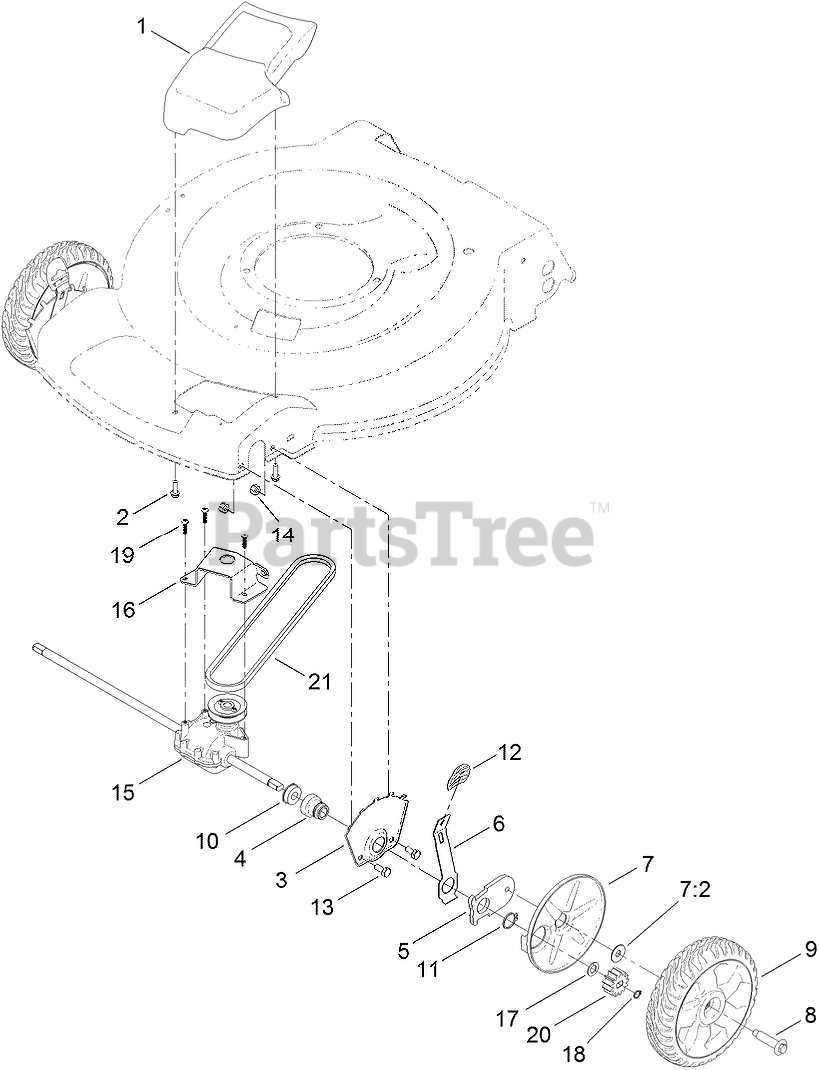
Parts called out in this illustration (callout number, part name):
1	COVER-BELT
2	SCREW-HWH
3	PLATE-HOC, FRONT
4	RETAINER-BEARING, HOC
5	ARM-PIVOT, FRONT
6	Arm-Spring
7	WHEEL COVER ASM
7:2	WASHER-STEPPED
8	BOLT-SHOULDER
9	8 INCH WHEEL ASM
10	BEARING-BALL
11	RING-RETAINING
12	Knob-Lever, HOC
13	SCREW-HH
14	NUT-LOCK, NI
15	TRANSMISSION ASM
16	BRACKET-TRANSMISSION
17	WASHER-THRUST
18	RING-RETAINING
19	SCREW-PLASTITE
20	GEAR-PINION, 13T
21	V-BELT
